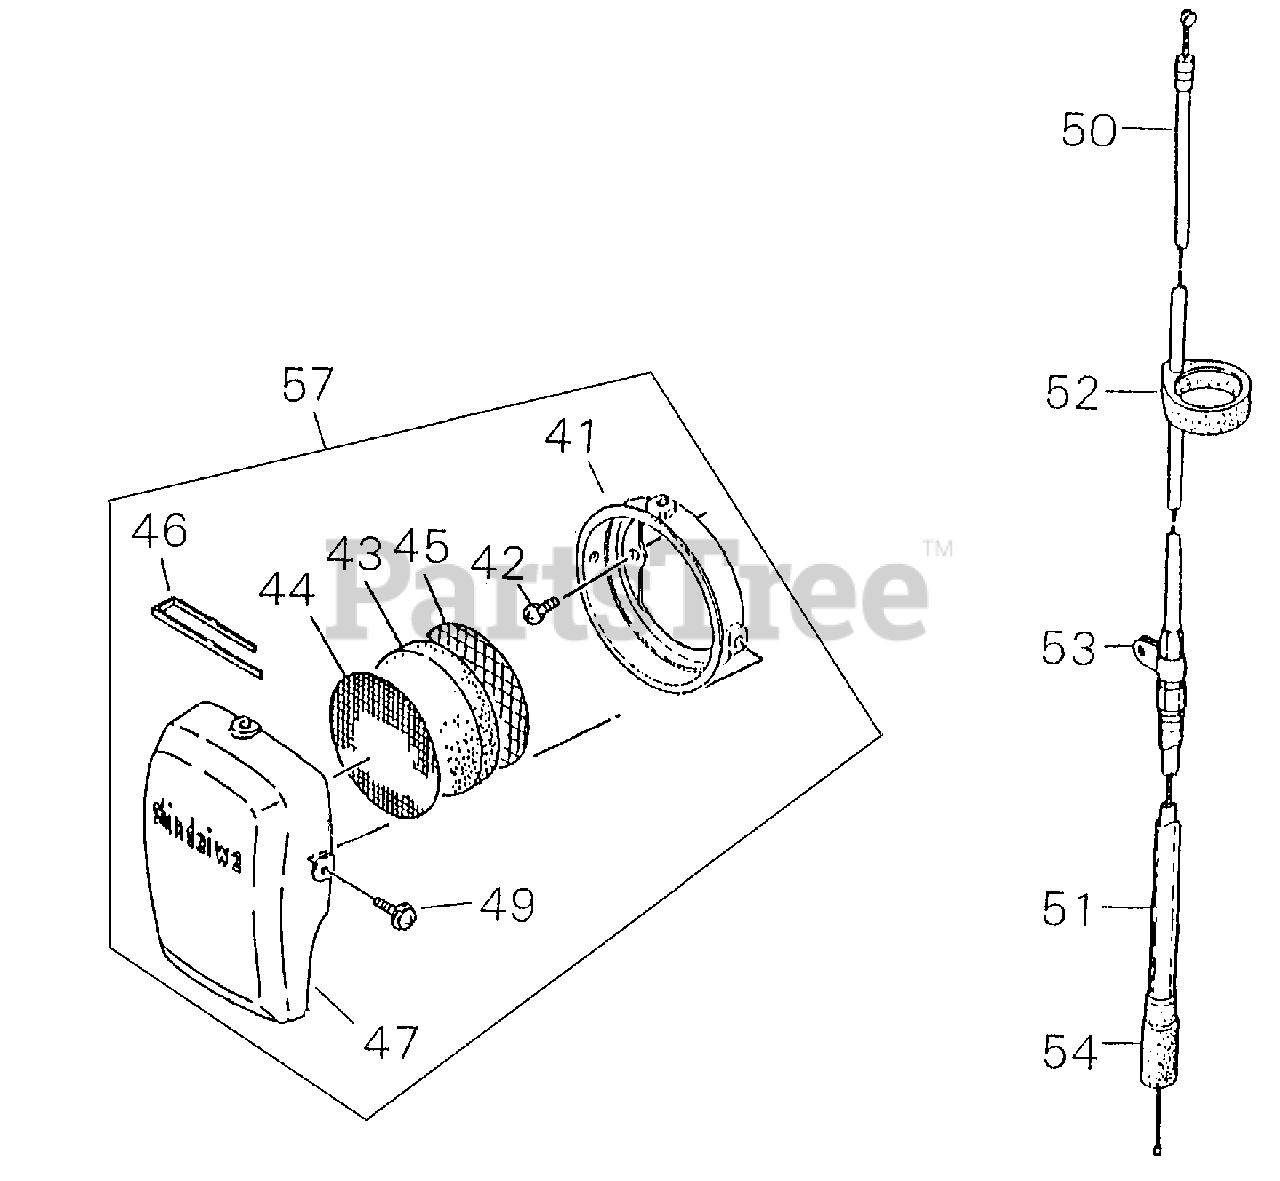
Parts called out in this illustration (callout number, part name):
41	CASE, AIR FILTER
42	SCREW
43	FILTER, AIR
44	SCREEN - FRONT
45	SCREEN, REAR
46	CLIP, FILTER RETAINING
47	COVER, AIR FILTER
48	LABEL, CHOKE
49	SCREW 4
50	CABLE, THROTTLE
51	PIPE
52	HOLDER, THROTTLE CABLE
53	CLAMP
54	CAP, CARBURETOR
57	AIR FILTER ASSY
